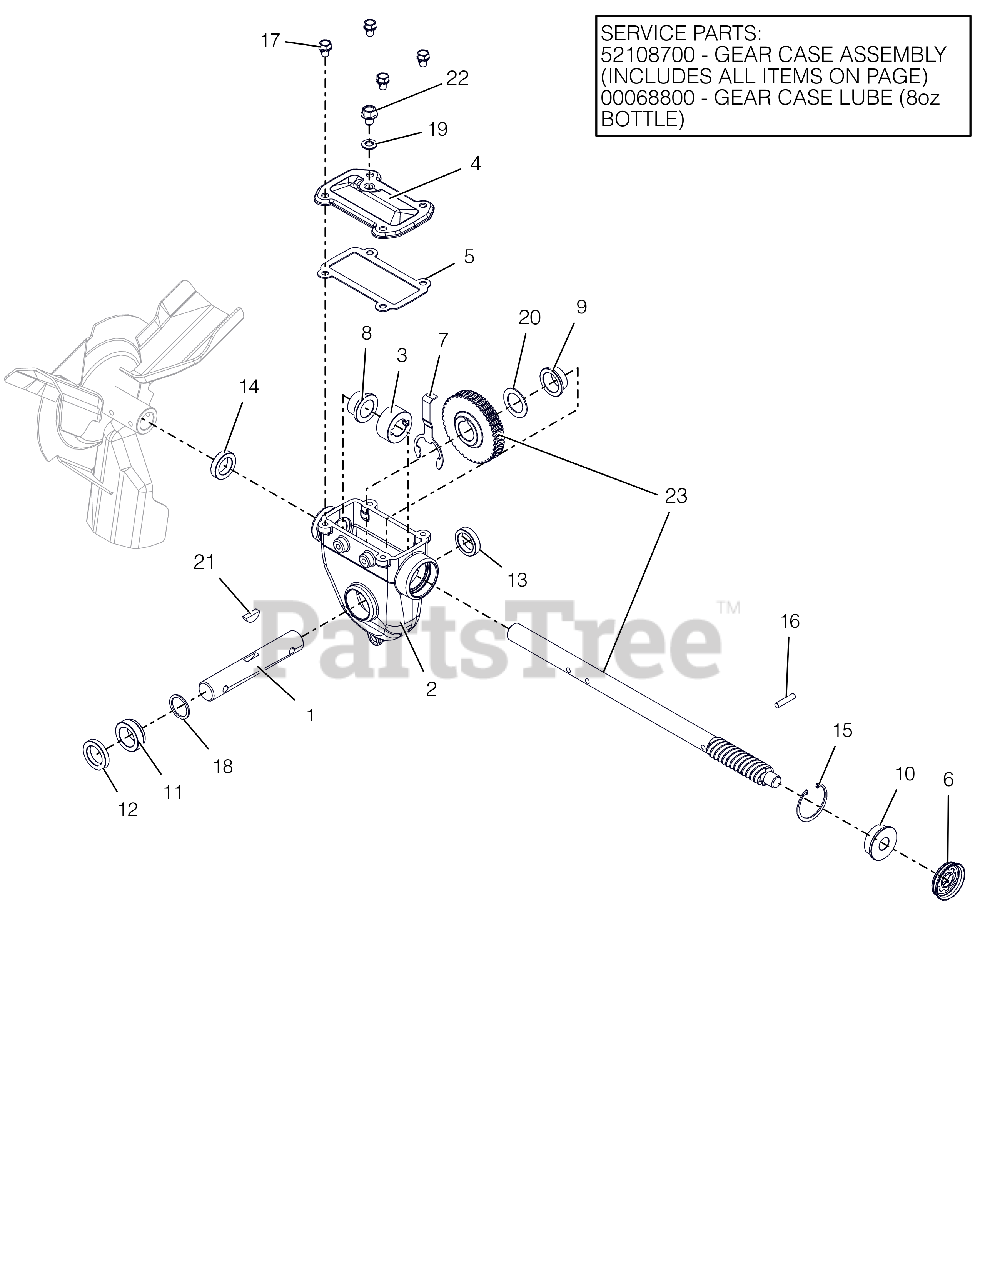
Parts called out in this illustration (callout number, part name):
1	RAKE SHAFT, SHORT-COMMON
2	GEARCASE, LARGE MACHINED
2	KIT, SERVICE - DLX GEAR CASE
2	ARIENS L3 LUBE, 8 OZ BOTTLE
3	THRUST COLLAR, .875"ID SLIPFIT
4	COVER, TOP - LARGE IRON
5	GASKET, TOP - LARGE GEARCASE
6	COVER, GEAR CASE 1.75"
7	BUSHING RETAINER, LARGE
8	BSHG-FLG .879X1.128X.75X1.45
9	BSHG-FLG 1.006X1.128X.555X1.45
10	BSHG-FLG .628X1.503X.58X1.725
11	BSHG-FLG LARGE, RIGHT
12	SEAL-OIL .999X1.500X.250 TBC29
13	SEAL-OIL .999X1.375X.312 TBC29
14	SEAL-OIL .873X1.375X.312 TBC29
15	RG-RTNG-INT 1.750X.062
16	PIN-STR .250X1.12 6150
17	BOLT, SEMS .31-18X.50 GR5 YWZC
18	WSHR-FL-STL 1.010X1.250X.068YZ
19	WSHR-BND-SEAL .38X.75X.11 GALV
20	WSHR-FL-STL 1.010X1.505X.062YZ
21	KEY-WDRF .25X.875 HRD #A
22	@SCR-ROLOK .38-16X.50 HWH YWZC
23	KIT, SERVICE-WORM SHAFT & GEAR
